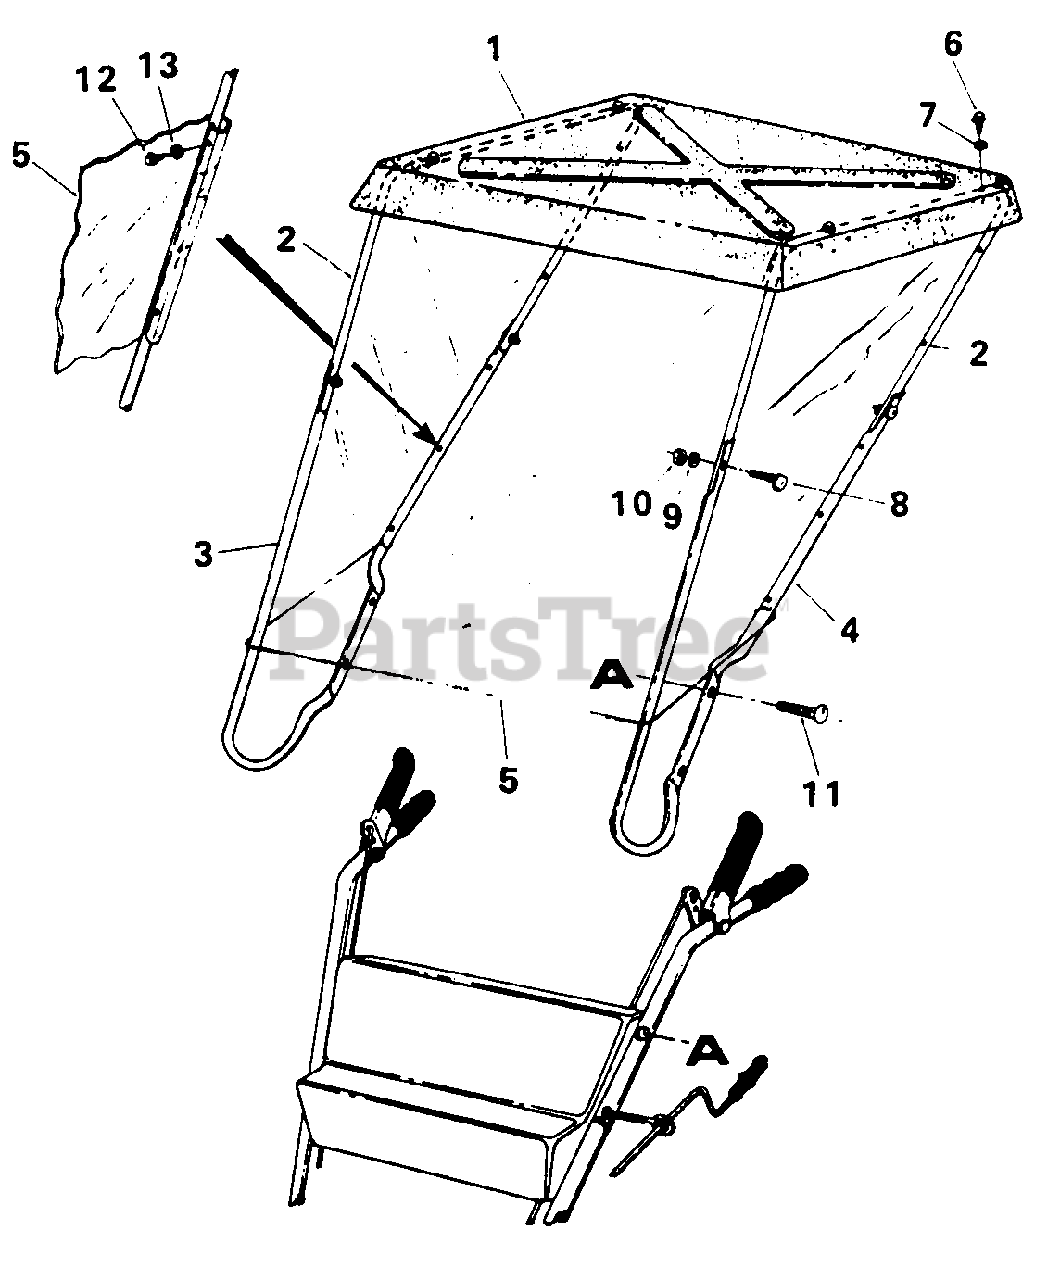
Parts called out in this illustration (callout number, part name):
1	Enclosure Roof
2	Upper Frame
3	Lower Frame-R.H.
4	Lower Frame-L.H.
5	Clear Plastic Windshield
6	Hex "AB" Tap Scr. 1/4 x .62" Lg.
7	Fl.-Wash. .281 " I.D. x.73" O.D.
8	Curved Hd. Carr. Bolt 5/16-18 x 1.38" Lg.
9	Lock Wash. 5/16" I.D.*
10	Hex Nut 5/16-18 Thd.*
11	Curved Hd. Carr. Bolt 5/16- 1 8 x 2. 25" Lg
12	Hex Wash. Hd. "AB" Tapp Scr. #10 x .50"
13	RubberWash..18" I.D. x.50 O.D.
